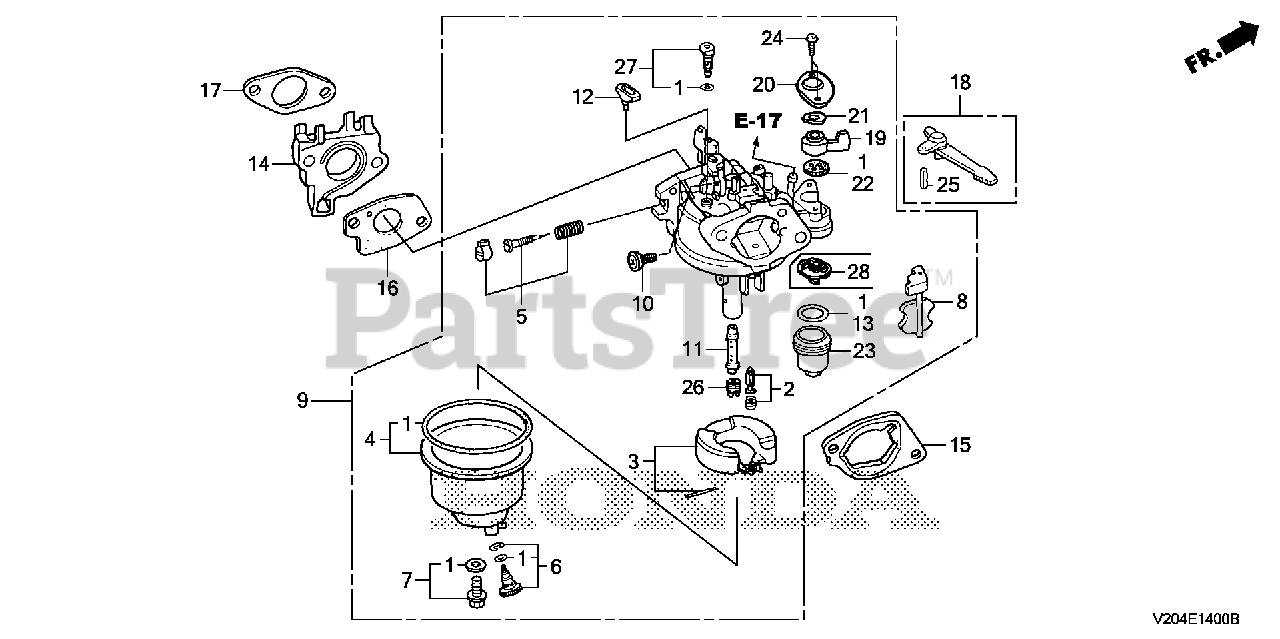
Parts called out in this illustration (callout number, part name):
1	GASKET SET
2	VALVE SET, FLOAT
4	CHAMBER SET, FLOAT
5	SCREW SET, PILOT
6	SCREW SET, DRAIN
9	CARBURETOR ASSY. (BE80U A)
10	SCREW, THROTTLE STOP
11	NOZZLE, MAIN
12	COLLAR, SETTING
13	GASKET, FUEL STRAINER CUP
14	INSULATOR, CARBURETOR
15	SPACER, CARBURETOR
16	GASKET, CARBURETOR
17	GASKET, INSULATOR
18	LEVER, CHOKE (STD)
19	LEVER, PETCOCK
20	PLATE, LEVER SETTING
21	SPRING, PETCOCK LEVER
22	GASKET, PETCOCK
23	CUP, FUEL STRAINER
24	SCREW, PAN (3X6)
25	PIN, SPRING (2X12)
26	JET, MAIN (#92)
26	JET, MAIN (#95)
26	JET, MAIN (#98)
27	JET SET, PILOT (#38)
28	FILTER, CUP
